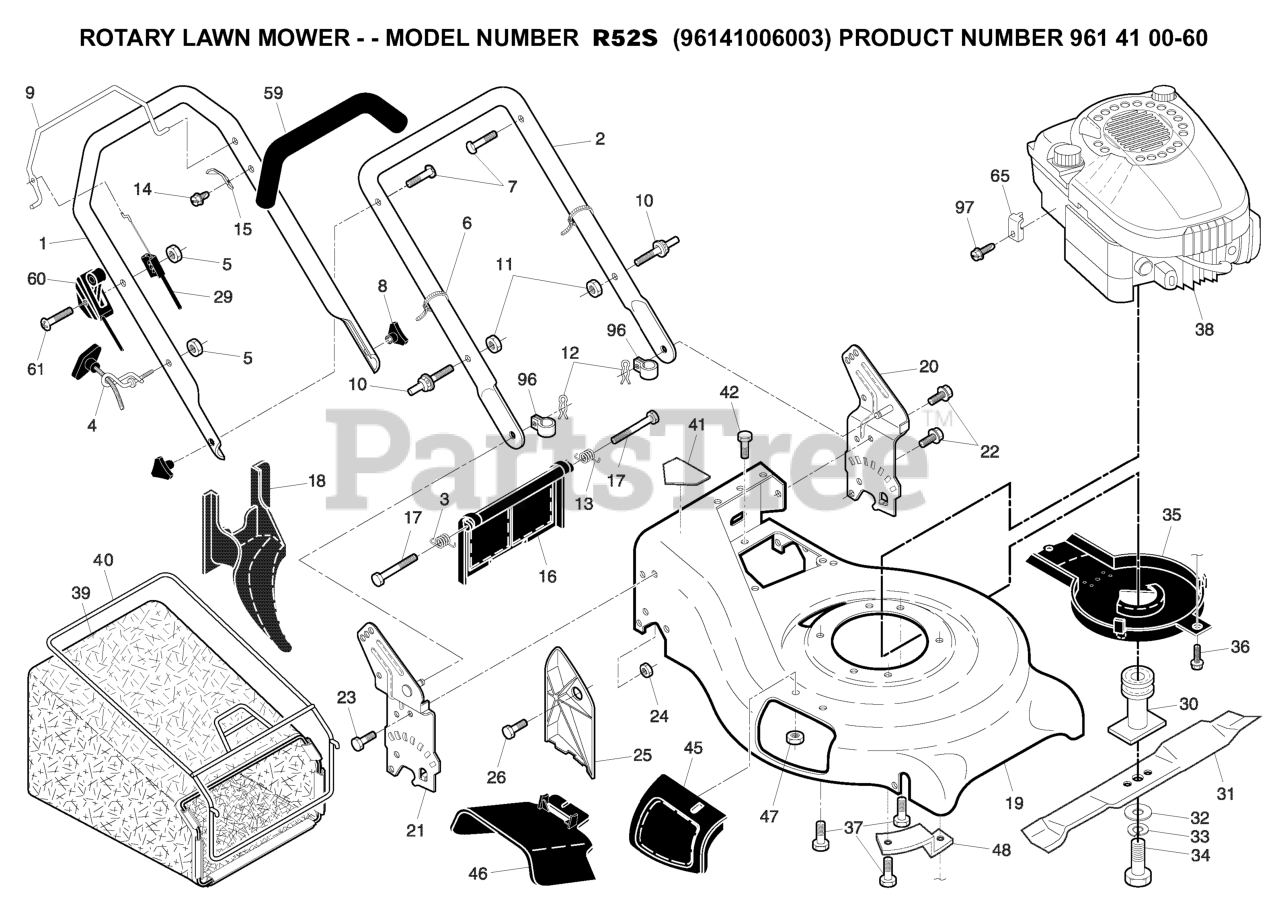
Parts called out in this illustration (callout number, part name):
1	HANDLE.UP.DLX.COMF.W/GRIP.GREY
2	HANDLE.LOWER.21.GREY
3	SPRING.RH.REAR.DOOR.21.RWGD
4	RB GUIDE.ROPE.STD.BLK.ZIN WSL
5	NUT
6	TIE GUIDE
7	BOLT, HANDLE 5/16-18X1.75
9	BAIL.CONT.COMF.PUSH.ORGANGE.RH
11	NUT.CENTERLOCK.5/16-
12	HAIRPIN COTTER
13	SPRING.LH.REAR.DOOR.21.RWGD
15	BRACKET UPSTOP
16	REAR DOOR ASSEMBLY
18	PLUG.MULCHER.RGD.21.
20	BRKT.ASM.HNDL.21.RWGD.LT
21	BRKT.ASM.HNDL
22	SELF-TAPPING SCREW 5/16-18X3/4
23	BOLT, HEX HEAD 5/16-18
24	NUT.71038.31-18.HEX.NYLOCK
25	CLIPPING DEFLECTOR
29	ENGINE ZONE CONTROL
30	BLADE ADAPTOR / PULLEY
31	BLADE.21.PUSH
32	WASHER,HARDEN
33	LOCKWASHER
34	SCREW, HEX HD 3/8-24 X 1-3/8
35	DEBRIS SHEILD
36	SCREW.HEX.WSH
37	BOLT 3/8-16X1-1/8
40	FRAME, GRASSBAG
41	DECAL.INTERNATIONL.CUTFINGER
45	MULCHER DOOR ASM.
46	DEFLECTOR, DISCHARGE
48	BRACKET
59	GRIP.HANDLE.FOAM
60	CONTRL.THROTTLE.
65	CABLE CLAMP(ENGINE)
96	CLIP.CABLE.BLK
97	SCREW.HEX.HEAD.WASHER.10-16
